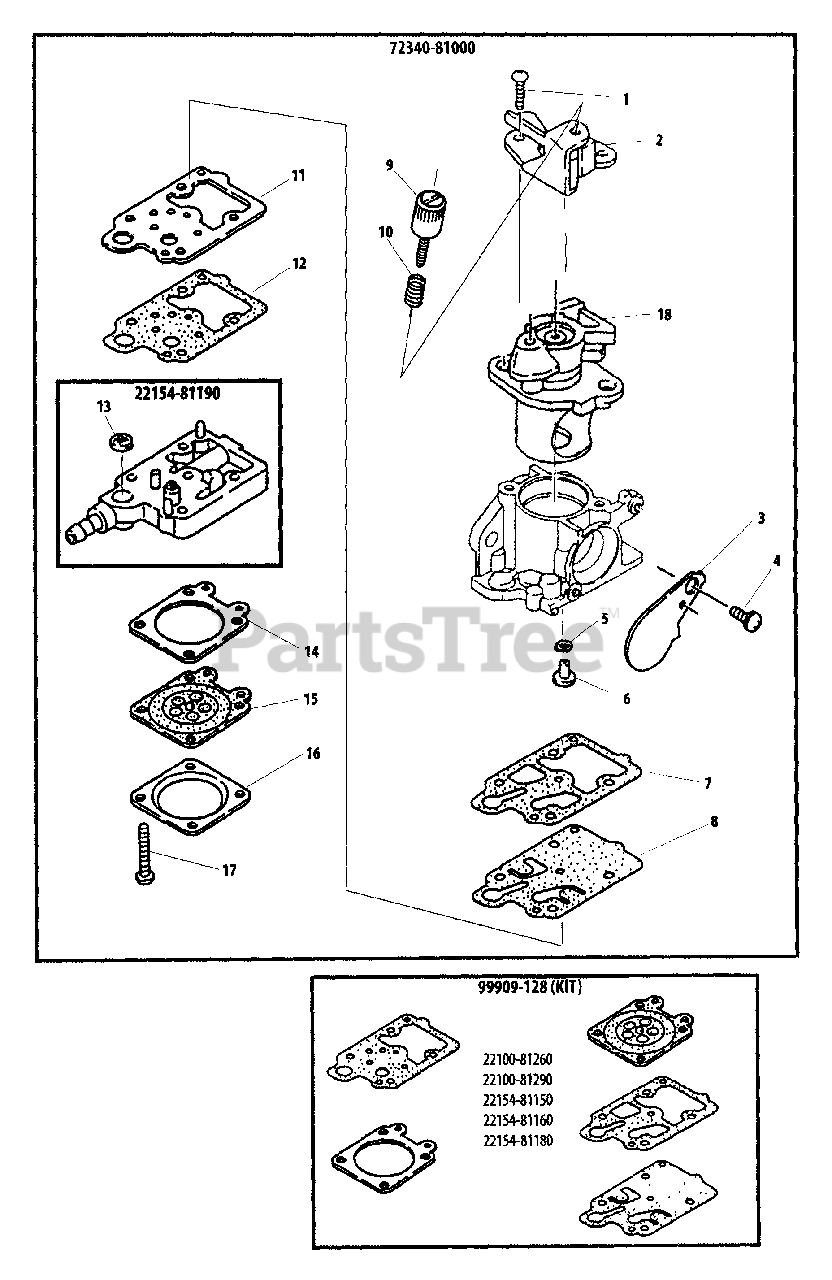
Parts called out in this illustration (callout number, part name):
2	BRACKET
3	VALVE, CHOKE
5	O-RING
6	JET, MAIN
7	GASKET, PUMP
8	DIAPHRAGM, PUMP
9	SCREW, IDLE ADJUST
11	PLATE, PUMP
12	GASKET, PLATE
13	STRAINER
14	GASKET, METERING
15	DIAPHRAGM, METERING
16	COVER, DIAPHRAGM
17	SCREW
18	THROTTLE VALVE ASSY
22154-81190	PUMP BODY ASSY
72340-81000	CARBURETOR
99909-128	DIAPHRAGM/GASKET KIT
